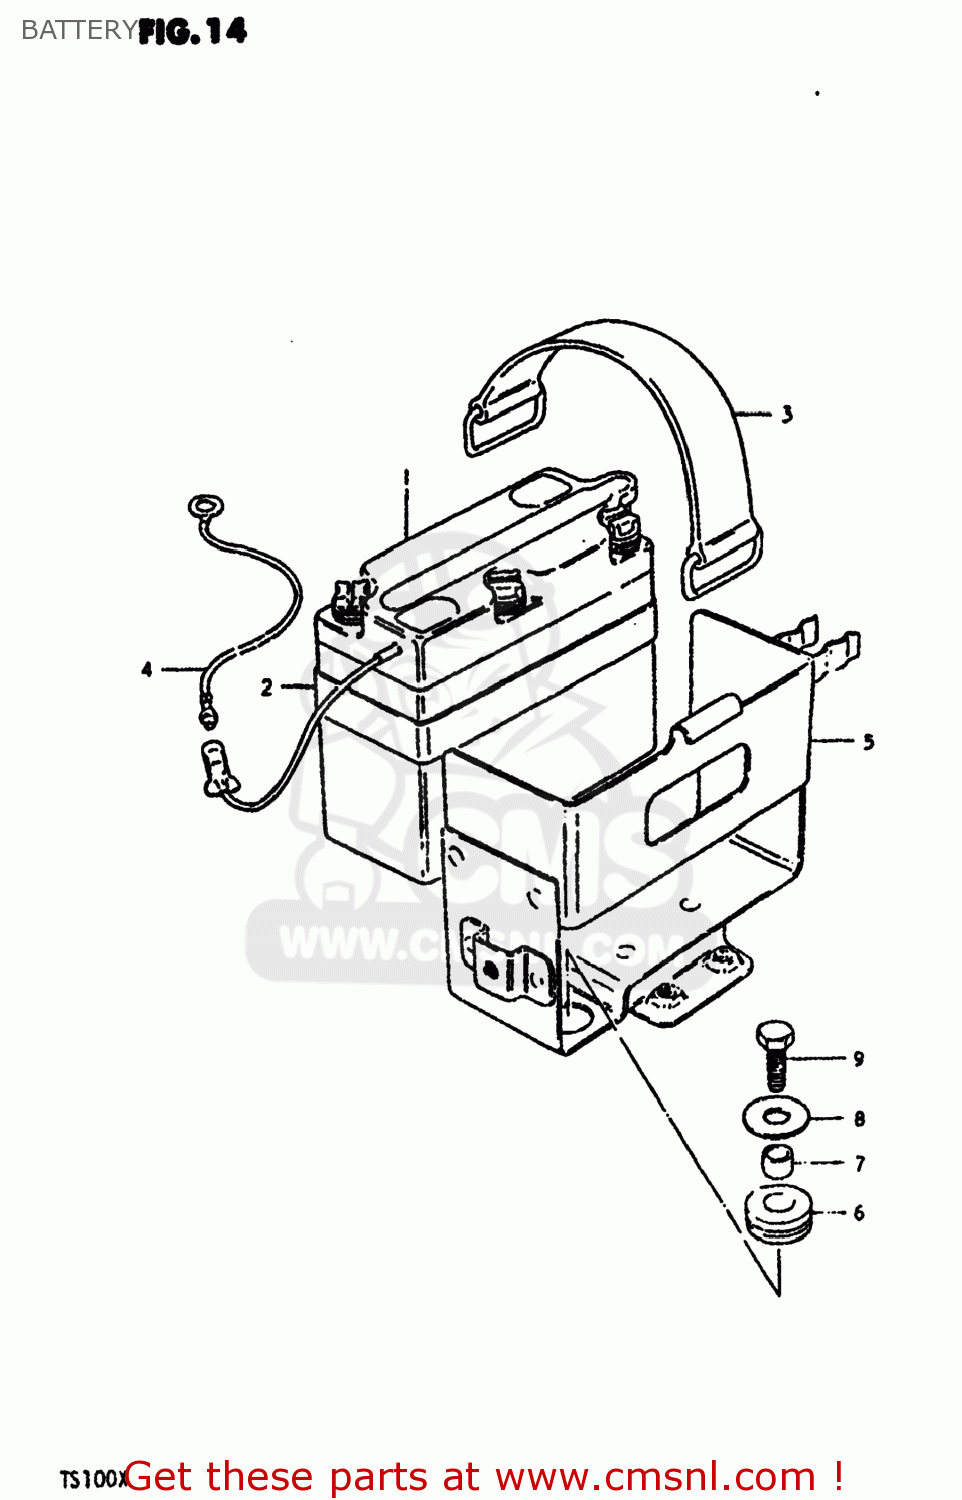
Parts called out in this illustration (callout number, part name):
1	BATTERY(6N4B-2A,6V4.2AH)
2	PROTECTOR,BATTERY
3	BAND
4	LEAD WIRE
5	HOLDER,BATTERY
6	CUSHION
7	SPACER (7X9X7)
8	WASHER (6.5X20X1.2)
9	BOLT, UPPER
